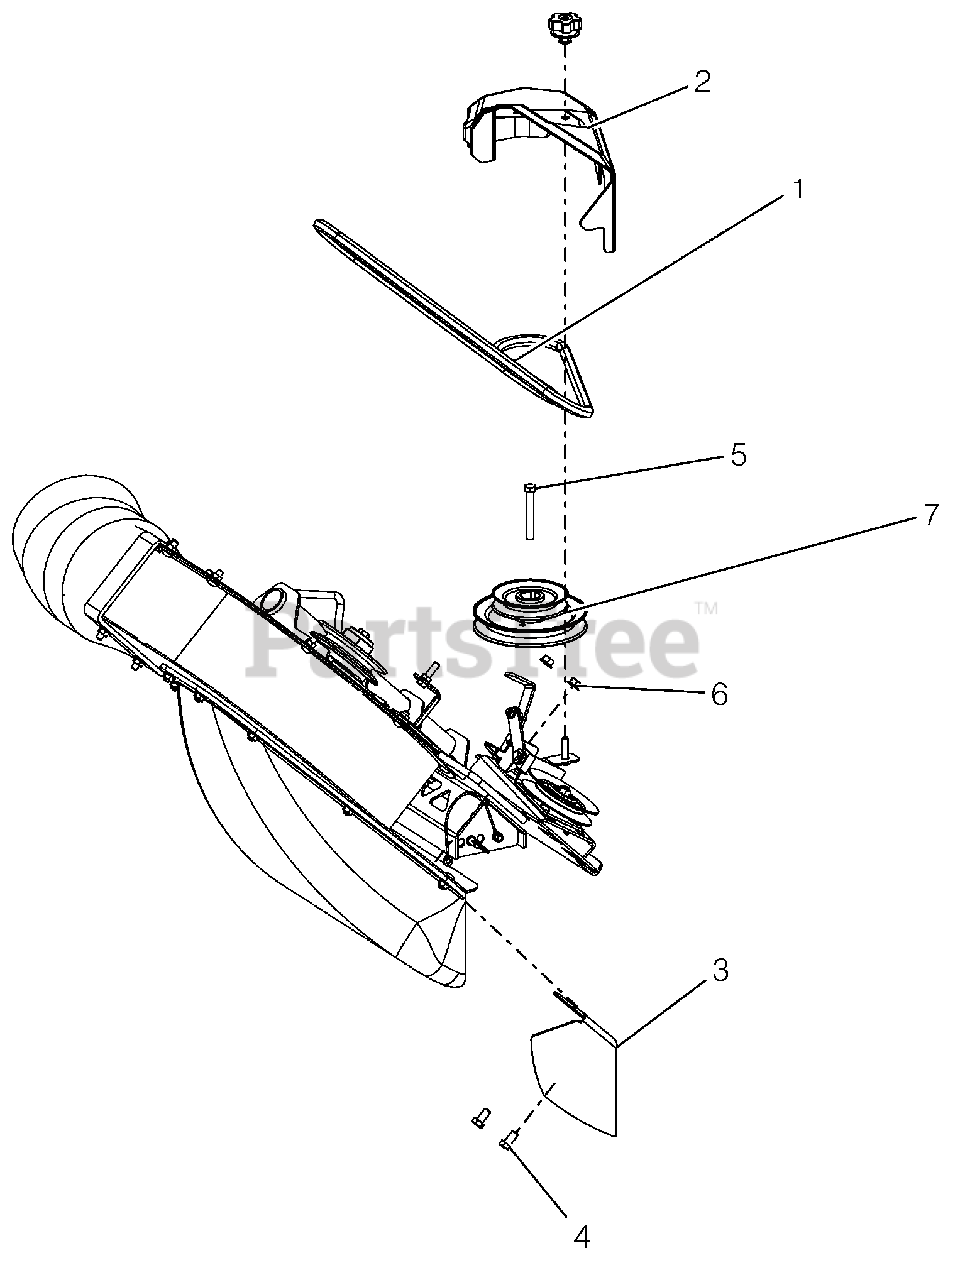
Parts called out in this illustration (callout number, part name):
1	HEX BELT, AA-WRAPPED
2	COVER, BELT 44-48 BLOWER
3	BAFFLE, BOLT-IN 44-48 BLOWER
4	@BLT-HEX .38-16X.75 GR5 YWZC
5	BLT-HEX .38-16X2.75 GR8 YWZC
6	@NUT-LK-TOP-FLG .38-16 YWZC
7	PULLEY, DOUBLE -1"IDX3.50"&6.0 (BLACK)
